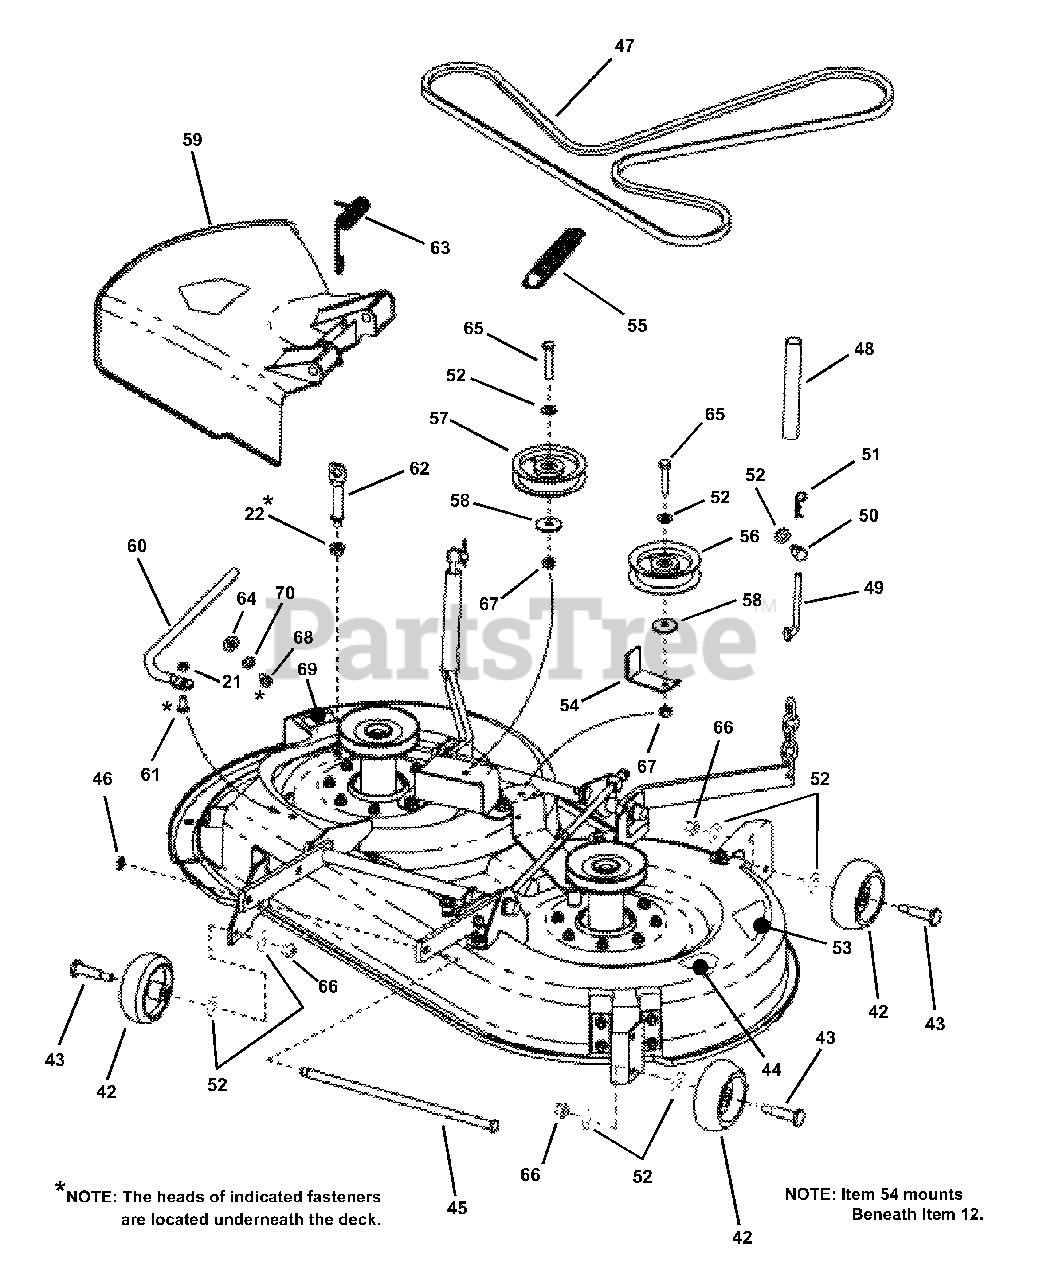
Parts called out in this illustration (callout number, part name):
21	NUT, 5/16-18 Hex Center Lock Grade 5
22	NUT, 3/8-16 Hex Flange Lock
42	WHEEL, 4 x 1-1/2" Offset
43	SHOULDER BOLT, 3/8-24
44	DECAL, CPSC- Heavy Adhesive
45	ROD, Deck Support
46	RING, .438 External Retaining
47	V-BELT, HA Section 89.8" Effective Length
48	COVER, Chain
49	ADJUSTER, Chain
50	SWIVEL, Adjustable
51	HAIR PIN, 3/32 x 1-1/2"
52	WASHER, 3/8" Flat
53	DECAL, 38" Deck
54	BELT GUIDE, 38/42" Decks
55	SPRING, Extension
56	IDLER, 4" O.D. Flat
57	IDLER, 4-1/8" O.D. Flat
58	WASHER, Cone
59	CHUTE, Discharge
60	ROD, Pivot, Side Discharge
61	BOLT, 5/16-18 x 3/4" Short Neck Carriage, Grade 5
62	ROD, Mounting, Side Discharge
63	SPRING, Torsion- Side Discharge
64	TEENUT, 5/16-18 Thread
65	SCREW, 3/8-16 x 2-1/4" Hex Head Cap, Grade 5
66	NUT, 3/8-24 Hex Center Lock, Grade 5
67	NUT, 3/8-16 Hex Center Lock, Grade 5
68	SCREW, 5/16-18 x 5/8" Pan Head
69	DECAL, Chute/Deflector Warning
70	WASHER, 5/16" I.D. x 11/16" O.D.
